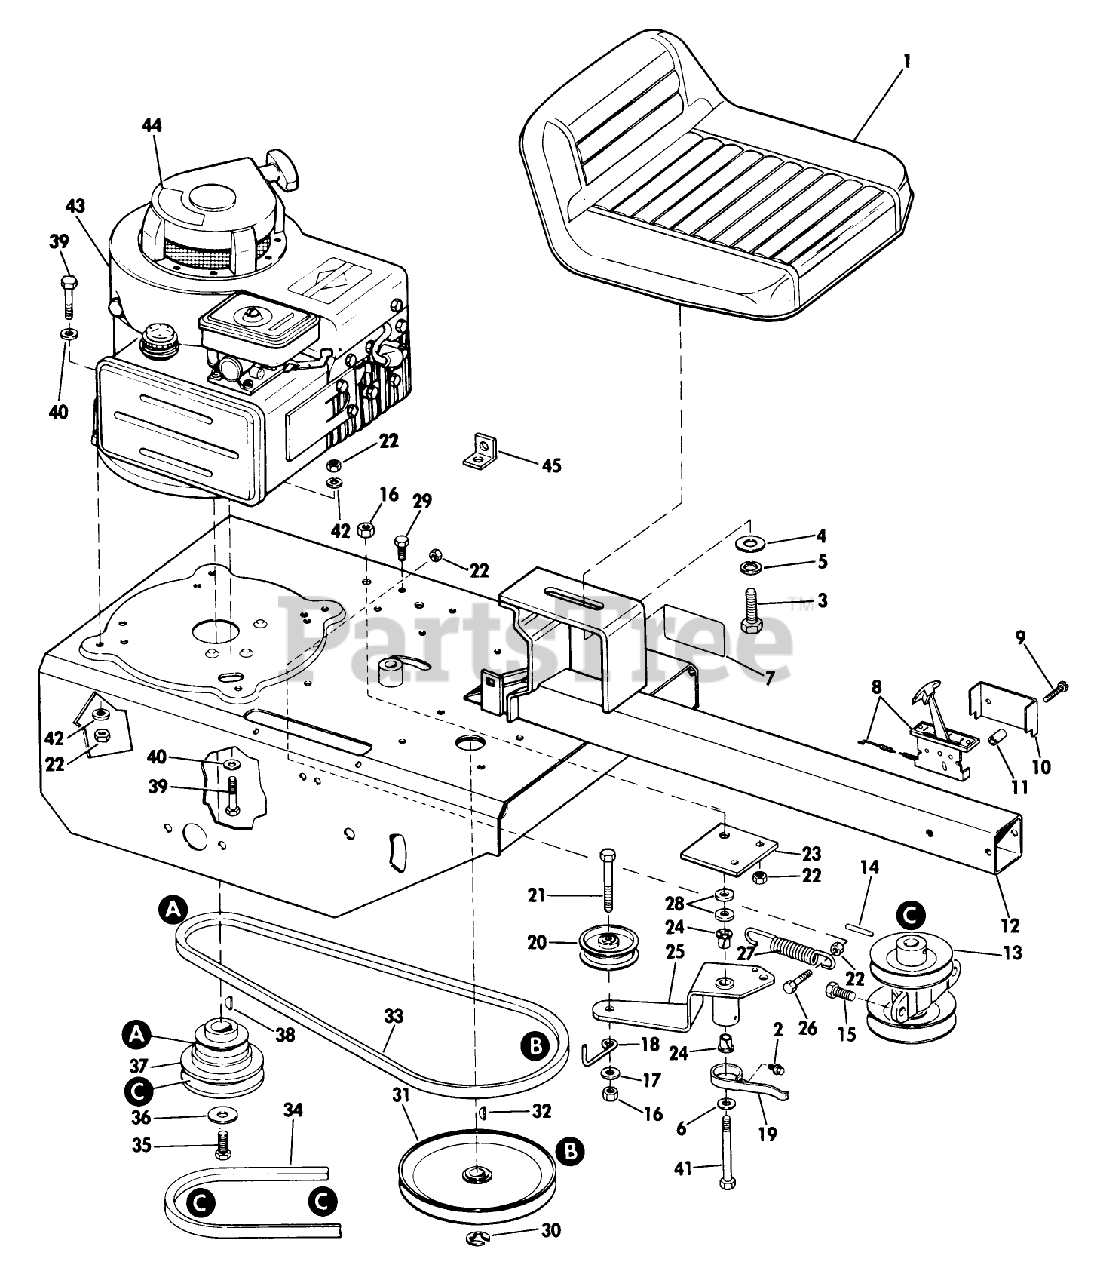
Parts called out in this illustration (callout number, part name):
7	Plate-Model No.
16	LOCKNUT
28	WASHER WROUGHT
